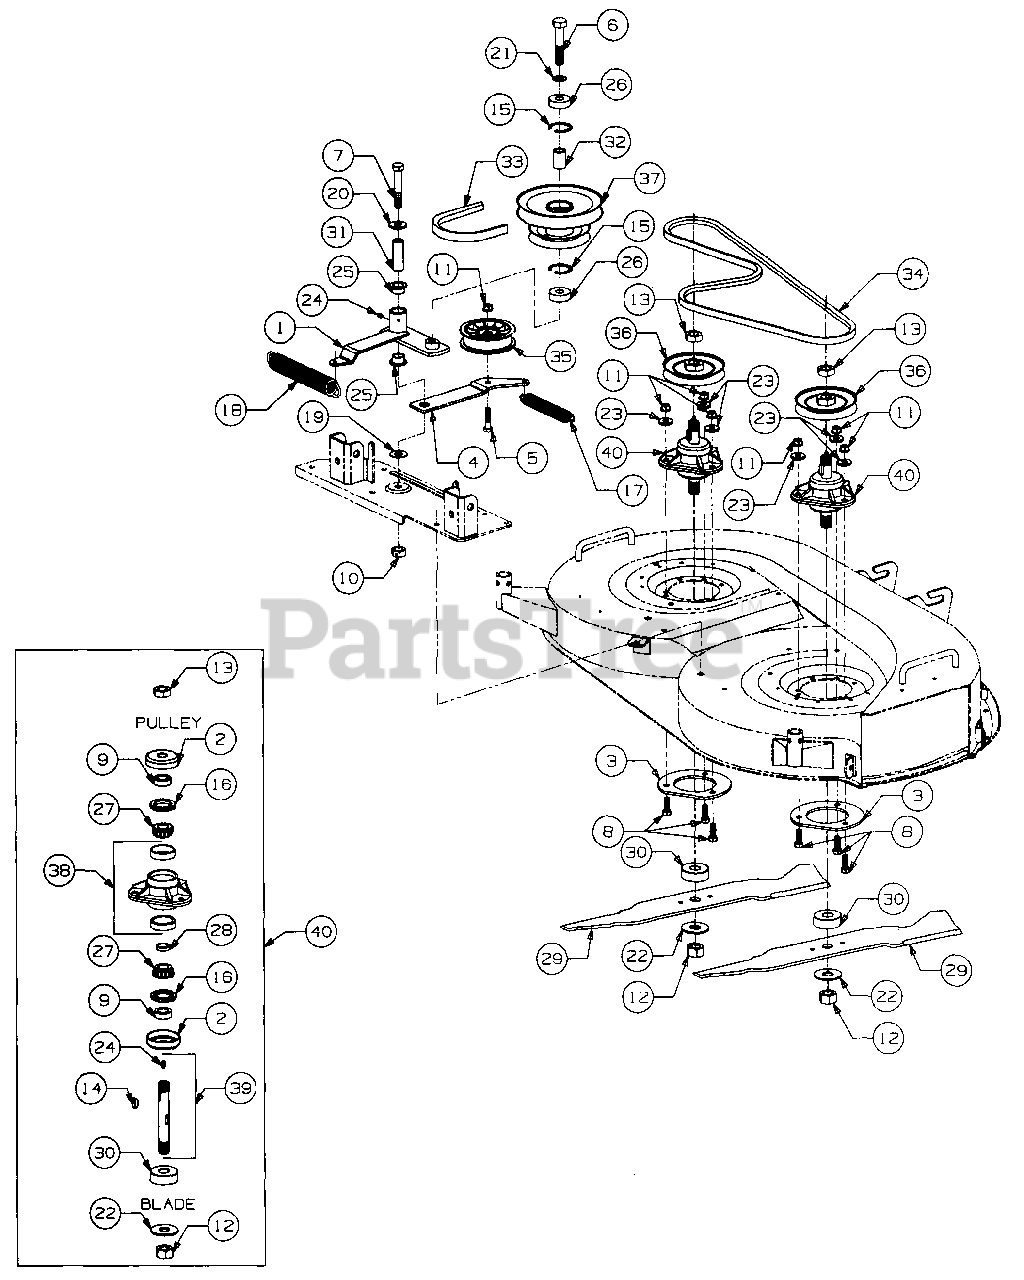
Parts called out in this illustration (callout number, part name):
2	Cup, Spindle Hdn
3	Plate, Spindle Mtg
5	Screw, Hex Cap, 3/8-16 x 1.5 Lg GR5
6	Screw, Hex Cap, 5/8-18 x 3.0 Lg GR5
7	Screw, Hex Cap, 1/2-20 x 3.0 Lg GR8
8	Screw, Hex Cap, 3/8-16 x 1.25 Lg GR5
9	Spacer, .755 x 1.25 x .44 Lg
10	Nut, Hex Center Lock, 1/2-20
11	Nut, Hex Flanged Lock, 3/8-16
12	Nut, Hex, 3/4-16 GR8
13	Nut, Hex Jam, 3/4-16 GR5
14	Key, #91 Woodruff, 1/4 x 3/4 Hdn
15	Snap Ring, Internal
16	Seal, Oil, 1.25 x 1.874 x .25
17	Spring, Extension, .88 OD x 6.12 Lg
18	Spring, Extension, 1.25 OD x 8.15 Lg
19	Washer, Flat, .531 x 1.25 x .036 Thk
20	Washer, Flat, .531 x 1.25 x .100 Thk
21	Washer, Flat, .63 x 1.0 x .063 Thk Hdn
22	Washer, Flat, .781 x 2.0 x .1 05 Thk
23	Washer, Flat, .385 x 1.0 x .1 35 Thk
24	Fitting, 3/16 Drive Lube
25	Bearing, Flange, 3/4 ID x .53 Lg
26	Bearing, Ball, .62 ID x 1.57 OD x .44 Thk
27	Cone, Bearing
28	Spacer, Bearing
29	Blade, Low Lift, 21.20 Lg
30	Spacer
31	Spacer, Idler Brkt, .50 ID x .75 OD x 2.25 Lg
32	Spacer, Pulley, .635 ID x .88 OD x 1.25 Lg
33	Belt, PTO, B-Section x 112.4
34	Belt, Spindle, A-Section x 62 Lg
35	Pulley, Flat Idler, 3.5 OD
36	V-Pulley, 4.62 OD
37	Pulley, Double
38	Housing w/Cups, Spindle
39	Kit, Shaft w/Seal
40	Spindle Assy, Blade
